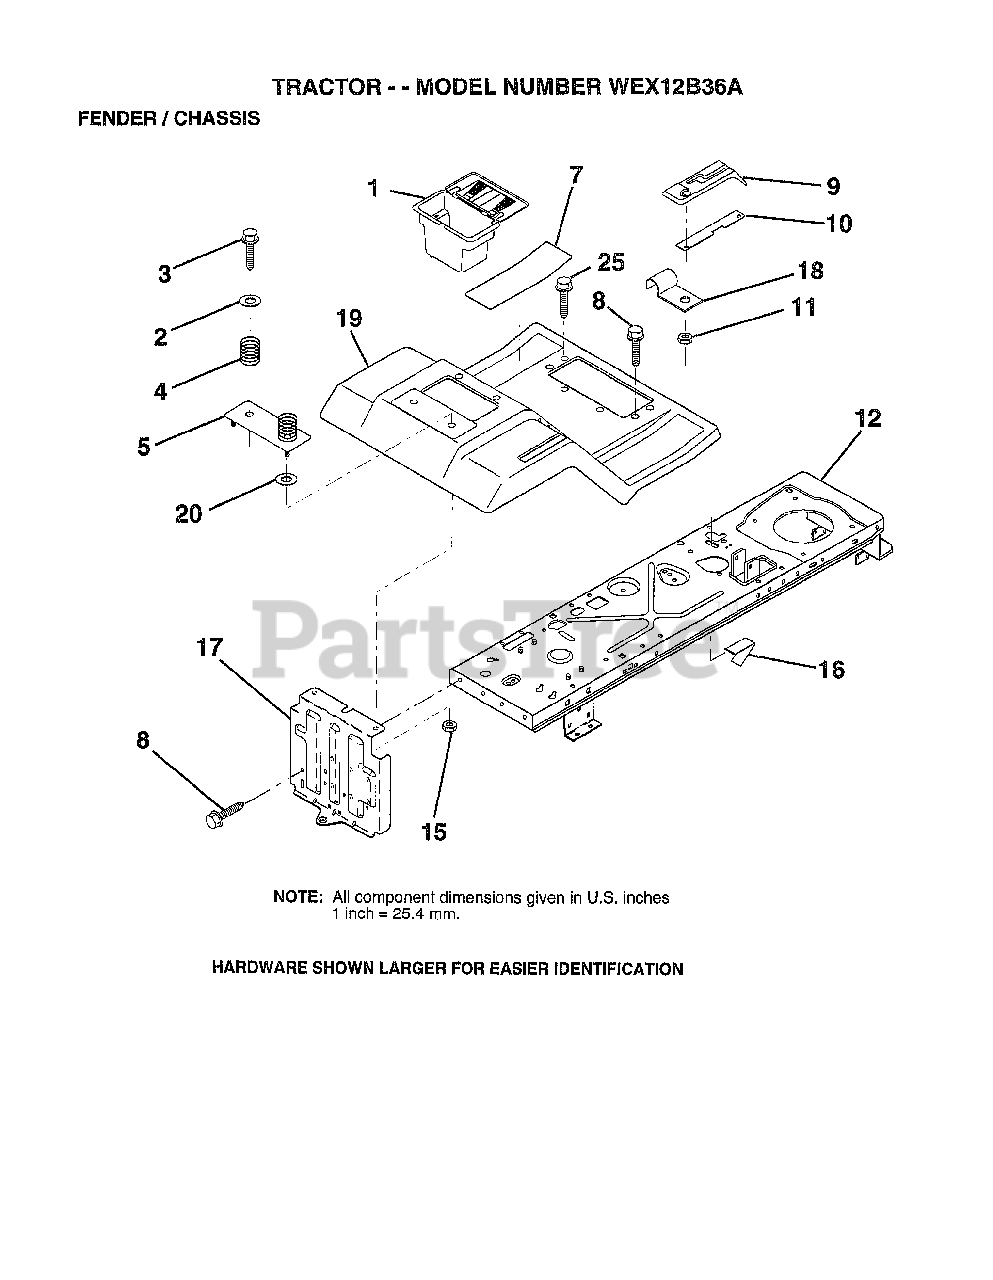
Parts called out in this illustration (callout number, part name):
1	"CASE,BATTERY.MECH"
2	WASHER
3	SCREW
4	SPRING COMPRESSIO
5	PLATE.FEND.LR.ASM
7	PAD FOOTREST
8	SCREW
9	CONSOLE, SHIFT CONTROL
10	PLATE LOCK SHIFT
11	NUT
12	CHASSIS.WELD.ASM.
15	NUT HXKEP 1/4X20
17	DRAWBAR ASM LR
18	"CLIP,INSULATOR"
19	FENDER/FOOTREST
25	SCREW
